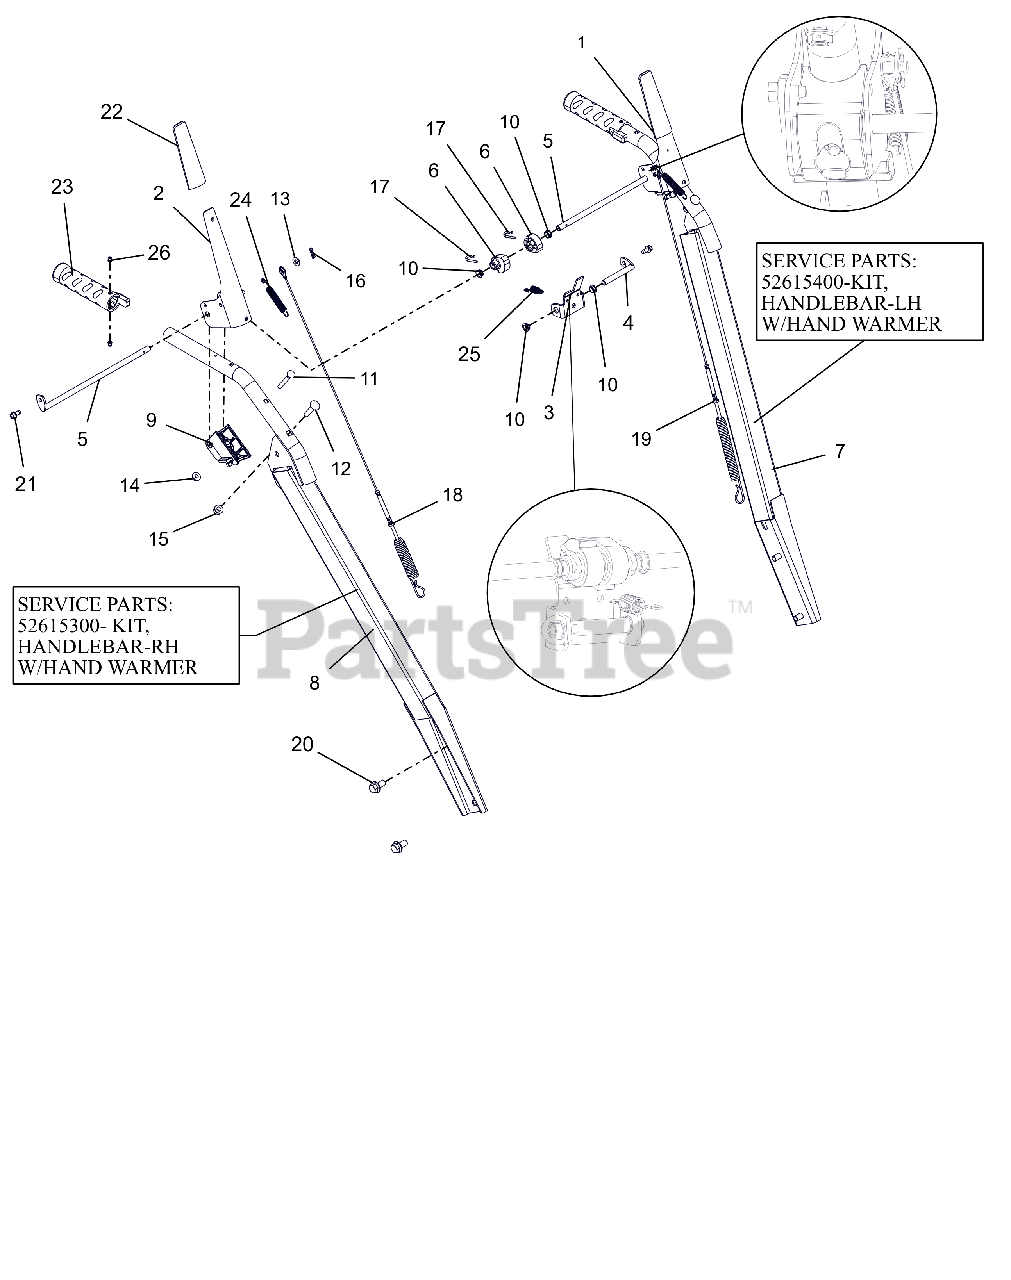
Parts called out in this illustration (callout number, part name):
1	LEVER, CLUTCH-LH
2	LEVER, CLUTCH-RH
3	BRACKET, INTERLOCK ARM
4	ROD, PIVOT - INTERLOCK
5	ROD, PADDLE MOUNT - PRO
6	CAM, INTERLOCK
7	HANDLEBAR, HEAVYDUTY-PRO LH
7	KIT, HANDLEBAR-LH W/WARM GRIP
8	HANDLEBAR, HEAVYDUTY-PRO-RH
8	KIT, HANDLEBAR-RH W/WARM GRIP
9	BLOCK, CLUTCH PADDLE
10	BUSHING, POLYLINER-.38 SNAPIN
11	BLT-RDHDXLSQNK .25-20X2.0 G5YZ
12	BLT,RHSN .31-18X1.50 G5 ZCC
13	WSHR,FLT .281X.625X.065 ZCC
14	NUT-LK-CTR-FLG .25-20 ZC120
15	NUT-LK-TOP-FLG .312-18 GF ZCC
16	PIN, HAIR #178 .06X.77 ZCC
17	PIN, SPRING CLIP
18	CABLE, AUGER (DELUXE & PRO)
19	CABLE, UPPER TRACTION
21	SCR-TAP .25-20X.50 HWH ZCC
22	SLEEVE, CLUTCH PADDLE-GRAY
23	GRIP,HEATED HANDLE-GRAY
24	SPRING, EXTENSION
25	SPRING-EXT .047X.438X1.45
26	RVT-POP #43 .125X.313 STL ZINC
